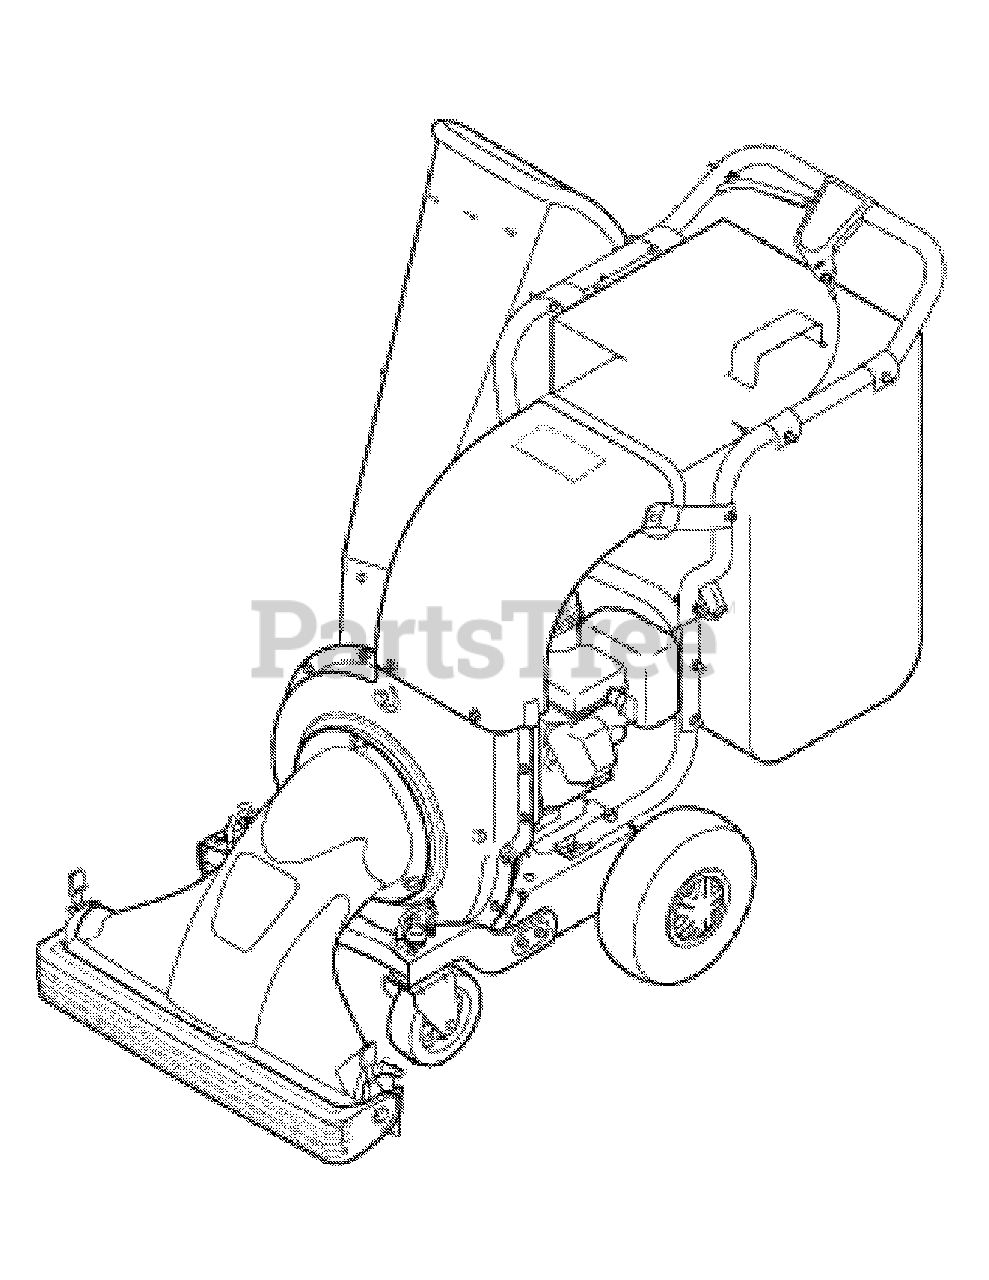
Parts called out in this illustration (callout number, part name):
NA	Fuel Filter
NA	Speed Control Cable
NA	Handle Knob
